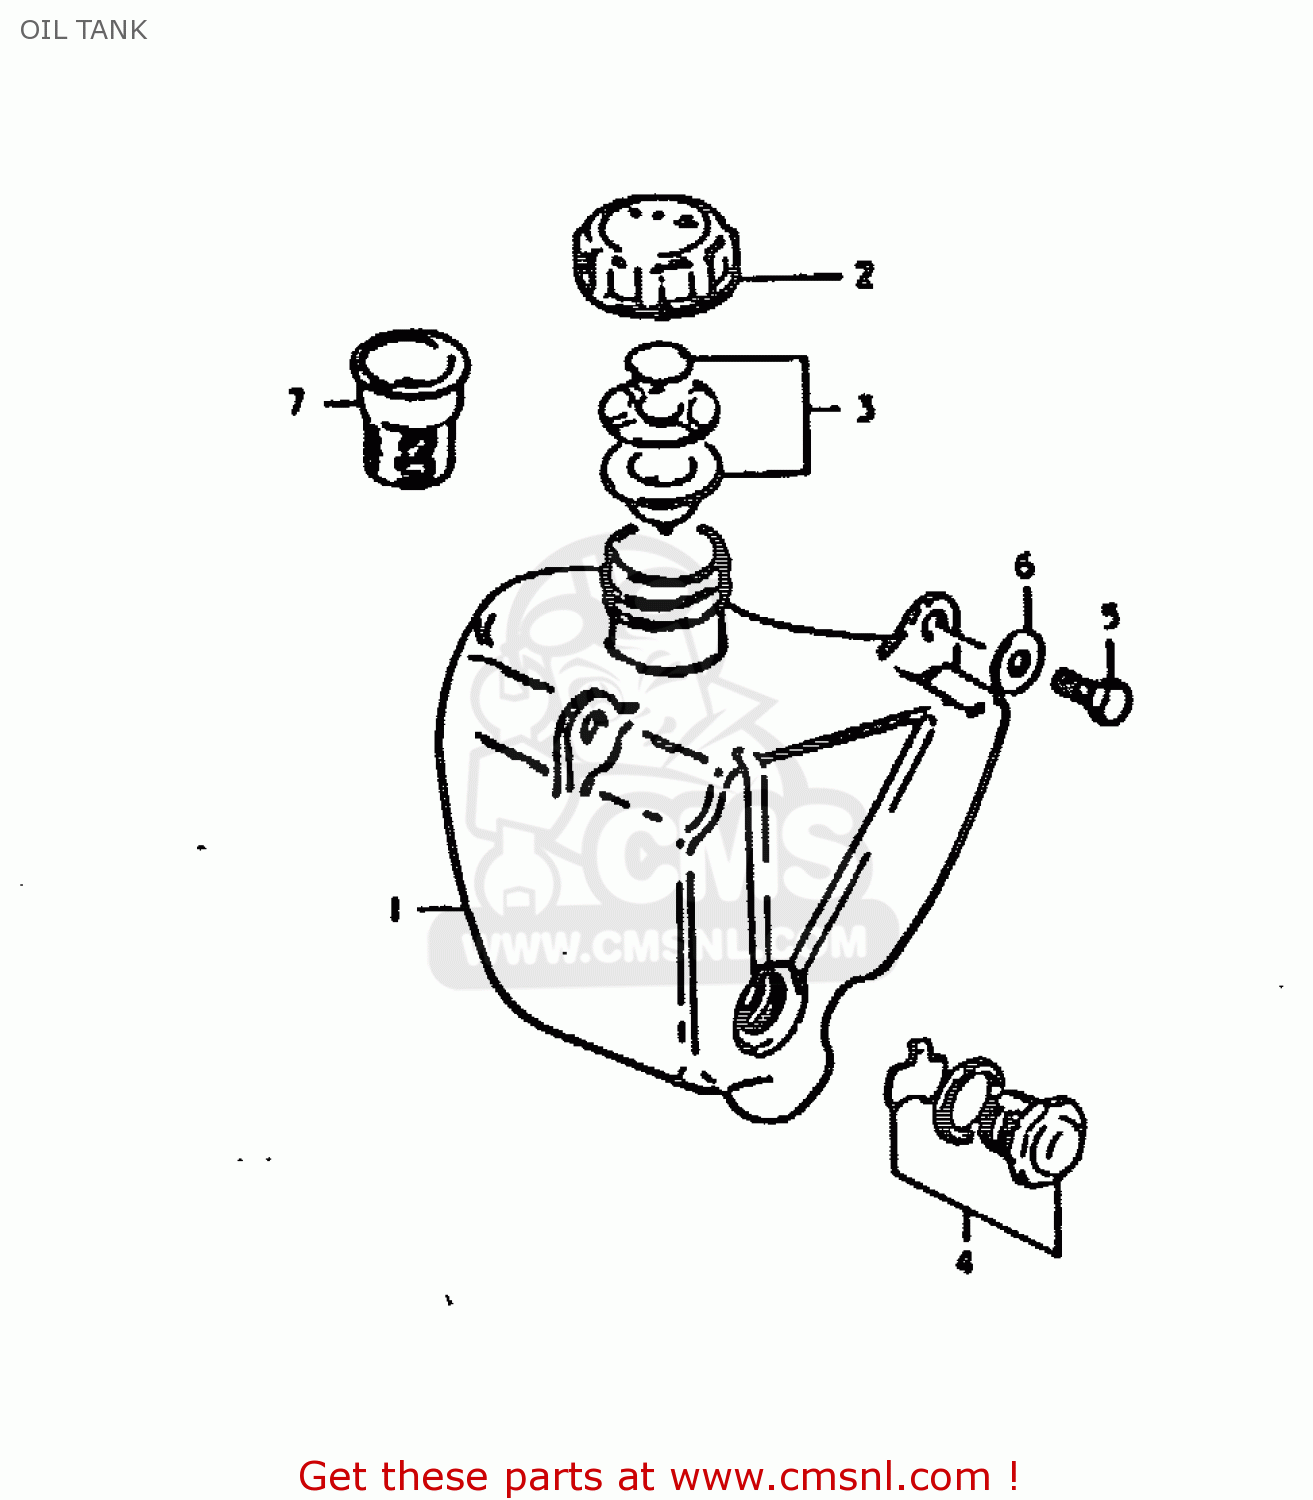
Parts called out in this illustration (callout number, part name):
1	TANK,OIL
2	CAP,OIL TANK
3	GASKET SET (NAS)
4	LENS SET,OIL LEVEL
5	BOLT, UPPER
6	WASHER
7	FILTER,OIL TANK INLET
